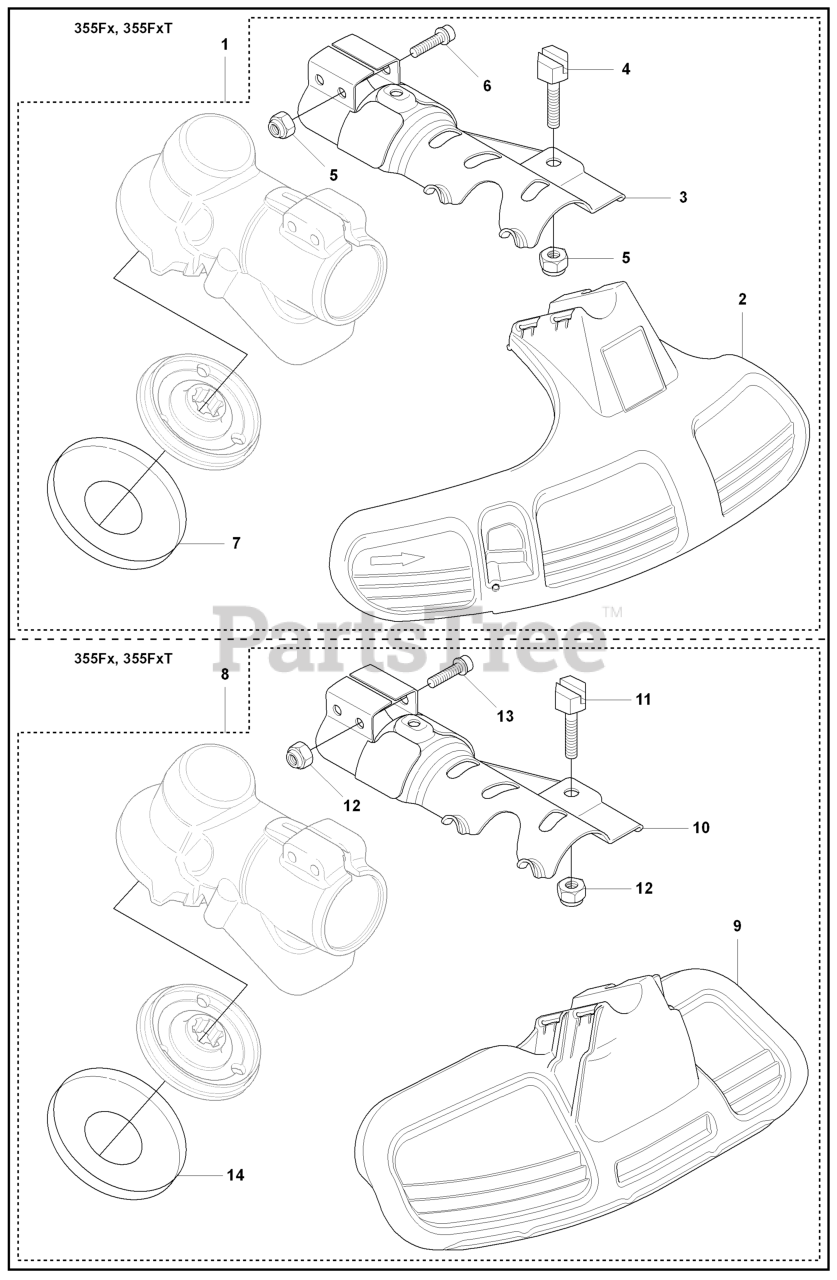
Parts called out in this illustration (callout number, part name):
1	GUARD ASSY
2	PROTECTION
3	ATTACHMENT PLATE
5	LOCKNUT M6
7	GRASS SEALING
8	GRASS BLADE GUARD ADAPTER INCL
9	BLADE GUARD GRASS
10	ATTACHMENT PLATE
12	LOCKNUT M6
14	GRASS SEALING
